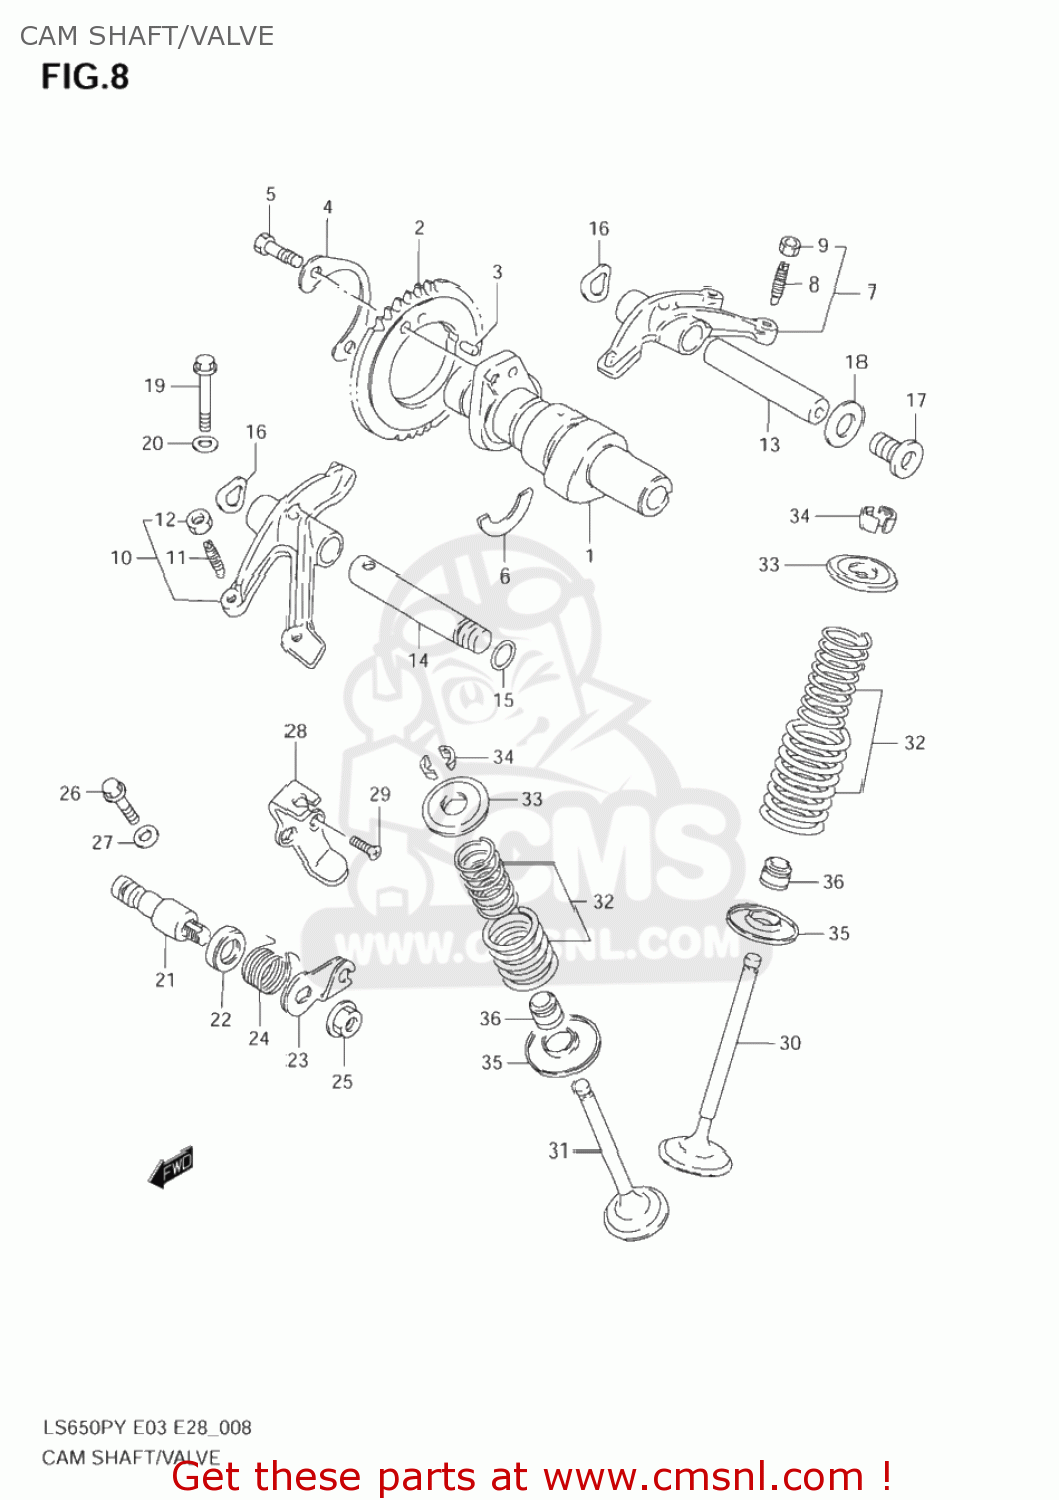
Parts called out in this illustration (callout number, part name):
1	CAMSHAFT
2	SPROCKET,CAMSHAFT
3	PIN(5X12.9)
4	WASHER,CAM CHAIN SPROCKET
5	BOLT(6X16)
6	C RING
7	ARM,INTAKE VALVE ROCKER
8	SCREW,TAPPET ADJUSTING
9	NUT,ADJUSTING SCREW
10	ARM,EXHAUST VALVE ROCKER
11	SCREW,TAPPET ADJUSTING
12	NUT,ADJUSTING SCREW
13	SHAFT,VALVE ROCKER ARM INTAKE
14	SHAFT,EXHAUST VALVE ROCKER ARM
15	O RING(D:1.9,ID:8.6)
16	WASHER
17	PLUG,14X12
18	GASKET(13.8X18.8X4.8) (NAS)
19	BOLT (GREEN)
20	GASKET(5.8X13X1.2) (NAS)
21	SHAFT,DECOMP,L
22	SEAL,OIL(10X20X6)
23	LEVER,DECOMP SHAFT,L
24	SPRING
25	NUT
26	BOLT(6X16)
27	GASKET(5.8X13X1.2) (NAS)
28	HOLDER,DECOMP CABLE,L
29	SCREW
30	VALVE,INTAKE
31	VALVE,EXHAUST
32	SPRING SET,VALVE
33	RETAINER,VALVE SPRING
34	COTTER,VALVE
35	SEAT,VALVE SPRING
36	SEAL,OIL(7X14.4X9)
